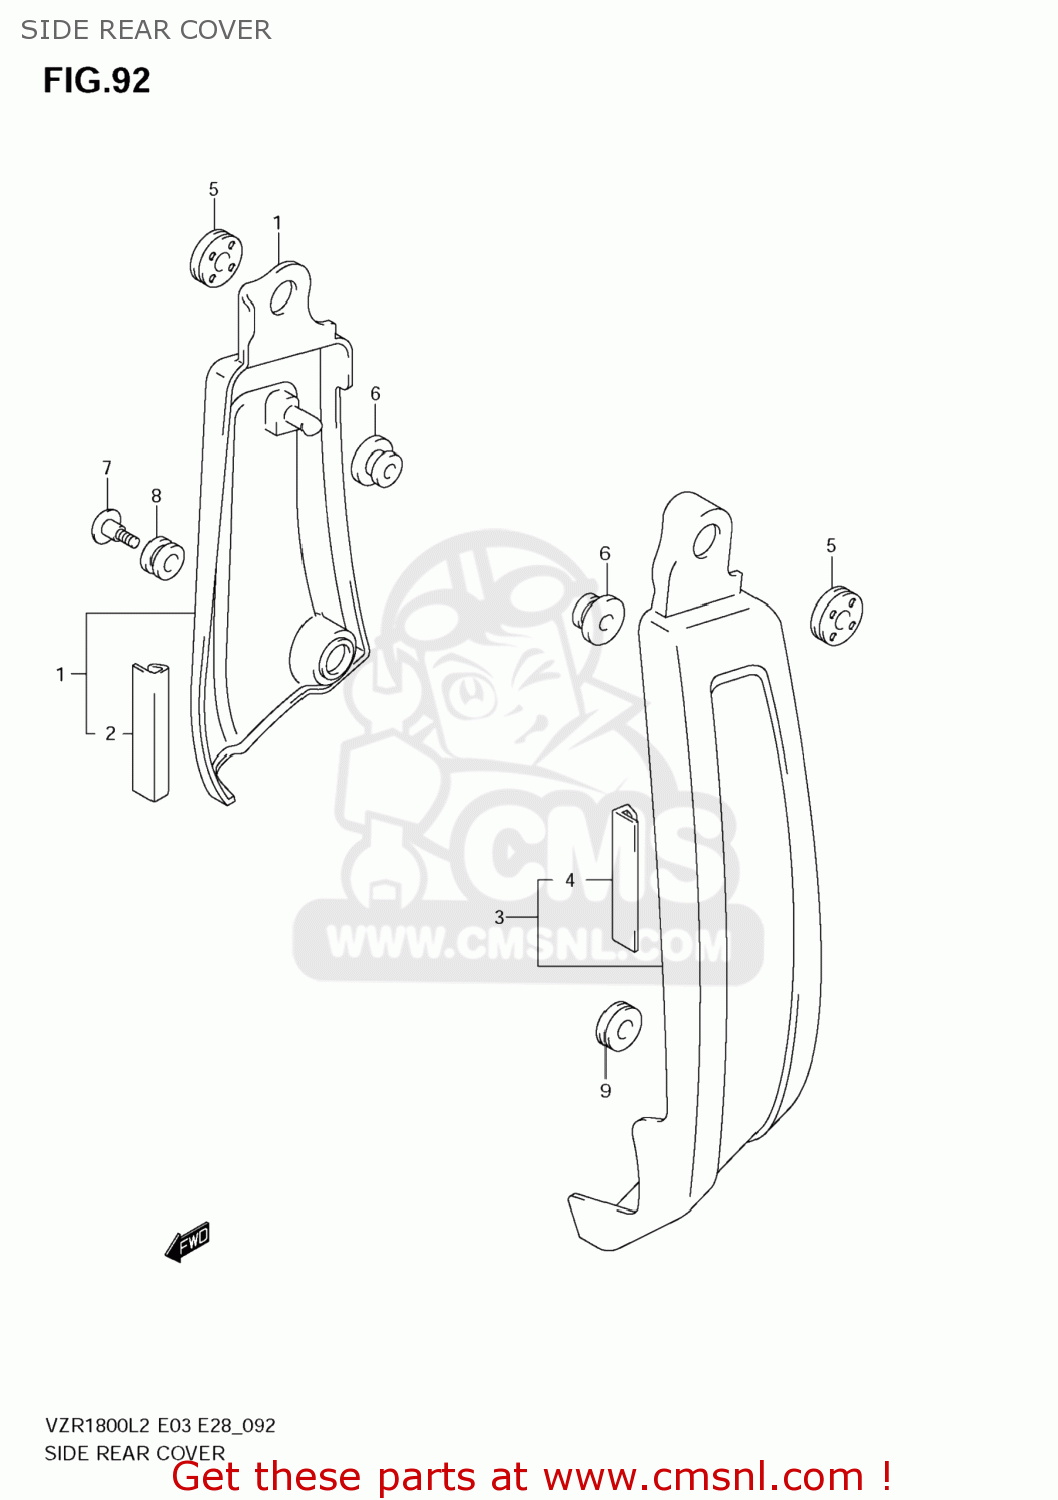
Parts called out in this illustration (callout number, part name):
1	COVER,SIDE RR,R
2	MOLDING
3	COVER,SIDE RR,L
4	MOLDING
5	CUSHION
6	CUSHION
7	SCREW(6X20)
8	CUSHION
9	CUSHION
